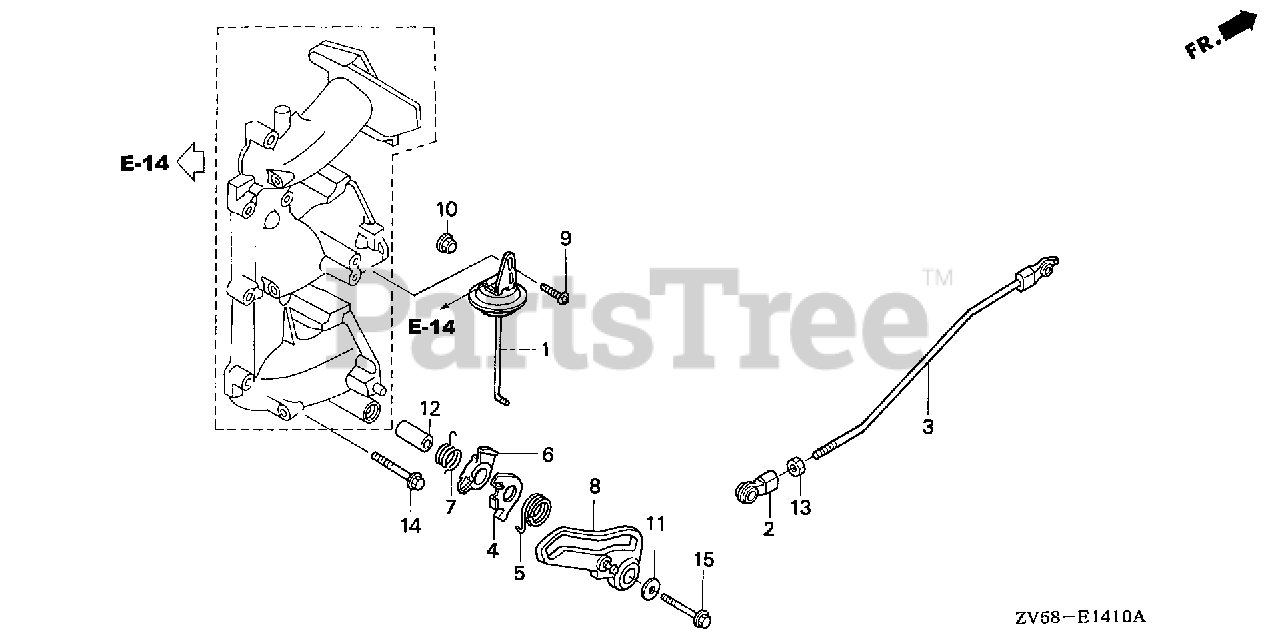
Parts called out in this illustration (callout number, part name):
1	DIAPHRAGM ASSY.
2	LINKAGE, PIVOT
3	ROD, THROTTLE
4	PLATE, ASSIST
5	SPRING, ASSIST
6	CAM, THROTTLE OPENER
7	SPRING, OPENER CAM RETURN
8	CAM, THROTTLE
9	BOLT, TORX (6X14)
10	NUT, CAP (6MM)
11	WASHER, PLAIN (6MM)
12	COLLAR (6.7X12.5X24)
13	NUT, HEX. (5MM)
14	BOLT, FLANGE (6X32)
15	BOLT, FLANGE (6X40)
